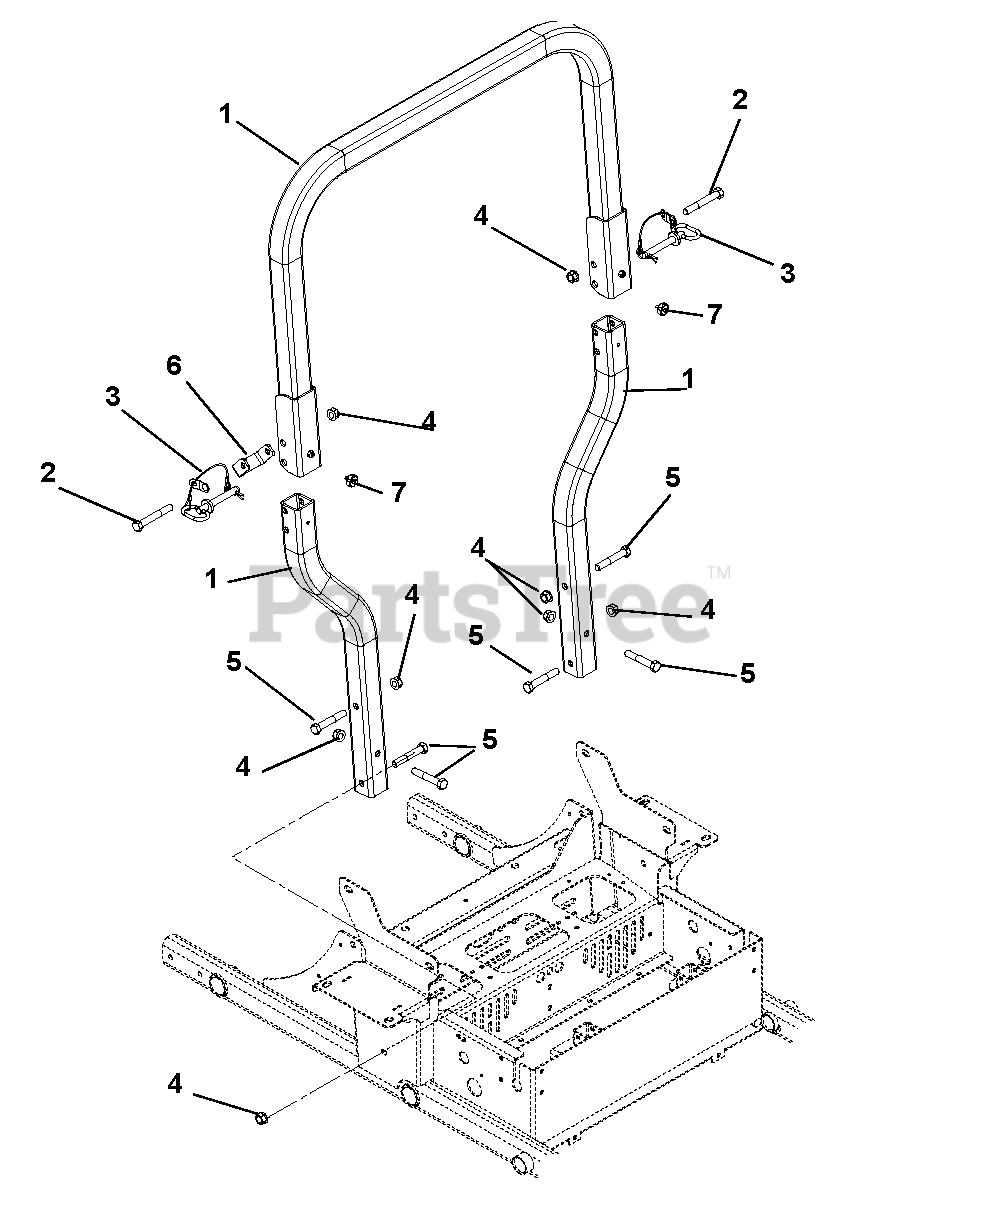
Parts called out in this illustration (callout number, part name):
1	ROPS, PT200 Replacement
2	Bolt, Hex .50-13 x 3.50 Grade 5
3	Assembly, ROPS Pin/Lanyard
4	Nut, Locking Top Flange .50-13
5	Bolt, Hex .50-13 x 3.00 Grade 5
6	Bracket, ROPS Stop, Pro-Turn
7	Knob, Round .312-18 x .750
